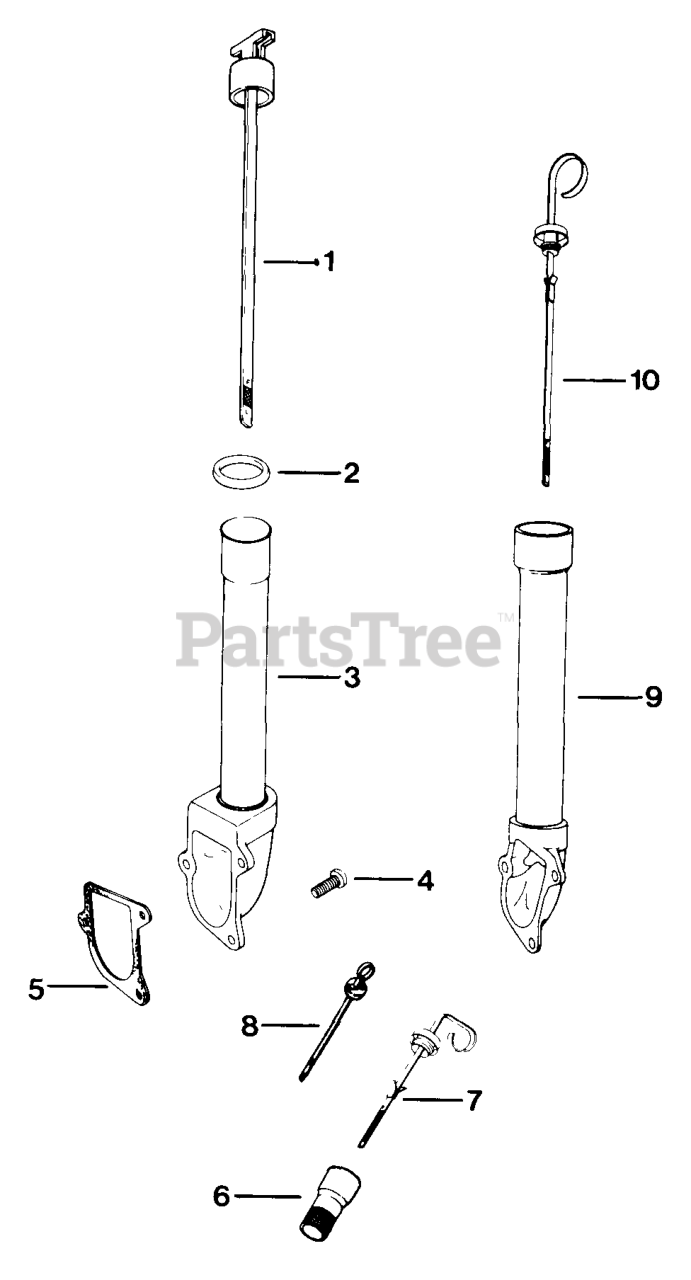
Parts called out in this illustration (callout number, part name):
1	DIPSTICK - DISCONTINUED
4	SCREW - DISCONTINUED
5	GASKET, OIL FILL ADAPTER
